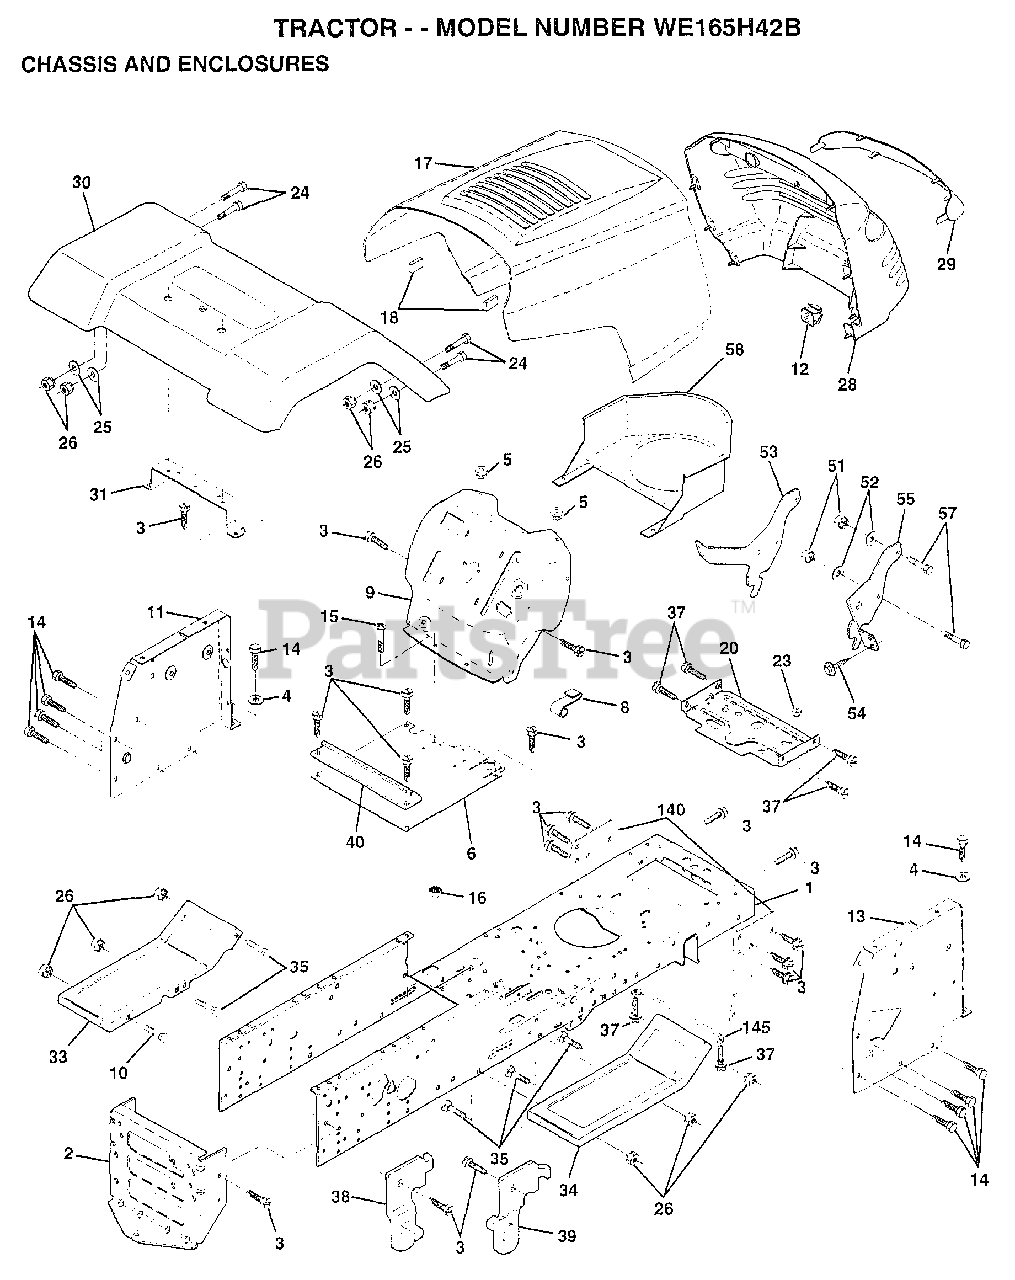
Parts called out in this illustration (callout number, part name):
3	SCREW
4	WASHER
5	BUMPER-HOOD/DASH
6	SADDLE
8	CLIP.RETAINER
9	DASH SILKSCREEN
11	"PANEL-DASH,LH"
12	CLIP.TINNERMAN
14	SCREW LT
15	SCREW
17	HOOD.STEEL.ASSY
20	"PLATE-MTG,BATT/FU"
24	BOLT
25	WASHER
26	NUT
28	GRILLE-MS428
29	LENS GRILLE
31	BRACKET SUPT FEND
33	FOOTREST.LH.LT/GT
34	FOOTREST.RH.LT/GT
35	BOLT
38	BRACKET ASM LH
39	BRACKET ASM RH
40	SPACER FENDER LT
51	NUT
52	WASHER
53	BRACKET.GRILLE.LH
54	SCREW.HEX.WS.HD
55	BRACKET.GRILLE.RH
58	AIR DUCT
140	BRKT SUSPENSION
145	"ROD POVOT,CHASSIS"
